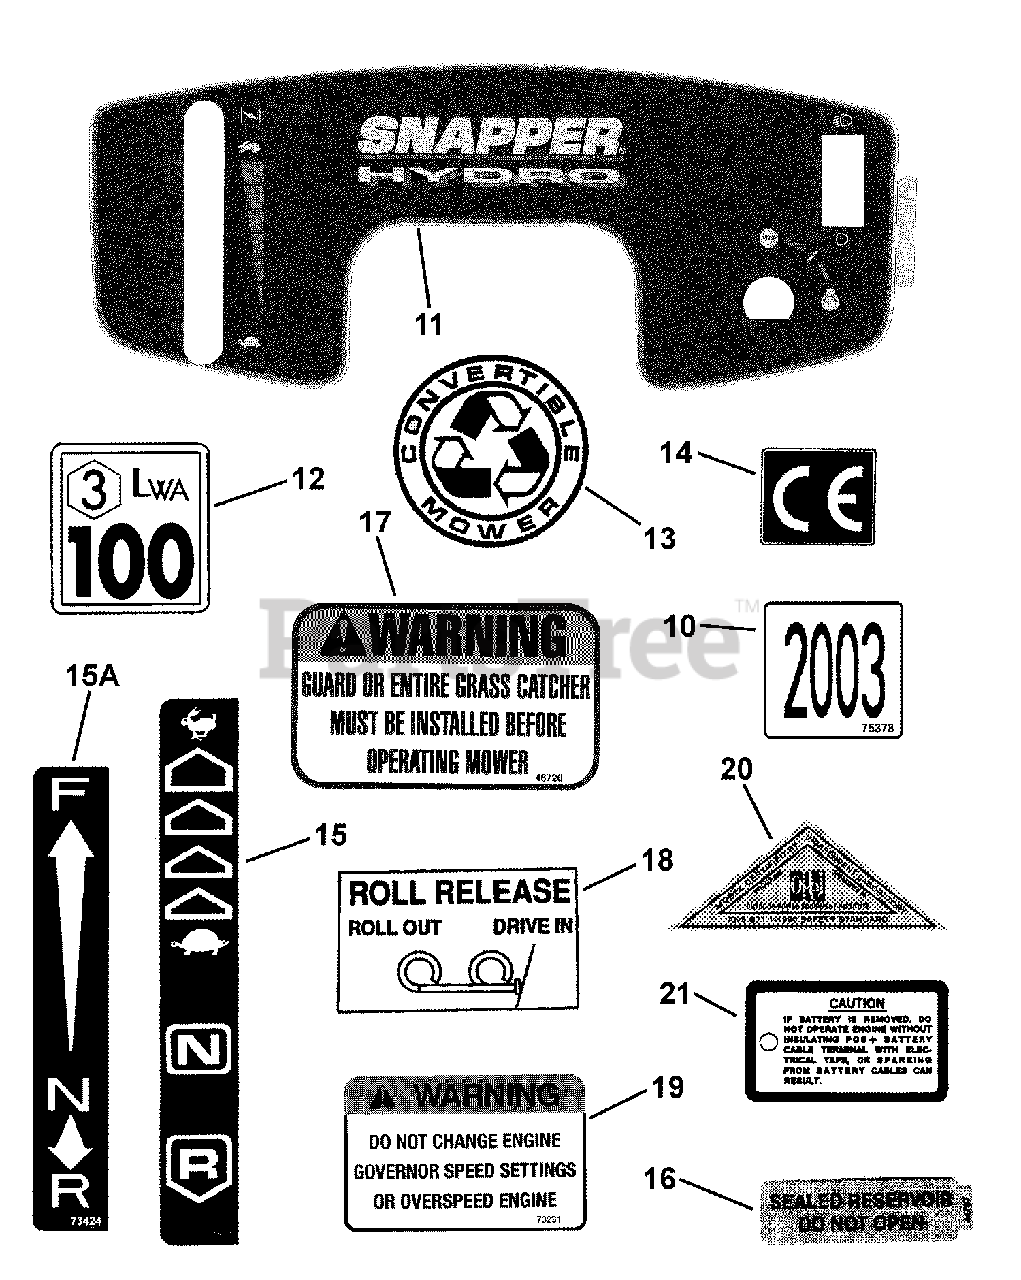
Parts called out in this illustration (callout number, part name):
10	DECAL, 2003 Year of Manufacture
11	DECAL, Console, Basic
11	DECAL, Console (2001 Model Year)
12	DECAL, Noise Control, Euro
13	DECAL, Medallion
14	DECAL, European Community
15	DECAL, Shift Cover
15A	DECAL, Shift Cover (Euro)
16	DECAL, Hydro Reservoir
17	DECAL, Chute/Deflector
18	DECAL, Roll Release
19	DECAL, Warning-Speed Setting 14, 16, & 18 HP ENGINES
19	DECAL, Warning-Speed Setting (German Version of above)
19	DECAL, Warning-Speed Setting (Dutch Version of above)
19	DECAL, Warning-Speed Setting (Spanish Version of above)
19	DECAL, Warning-Speed Setting (Italian Version of above)
19	DECAL, Warning-Speed Setting (French Version of above)
20	DECAL, OPEI Ride-On
21	TAG, Caution
